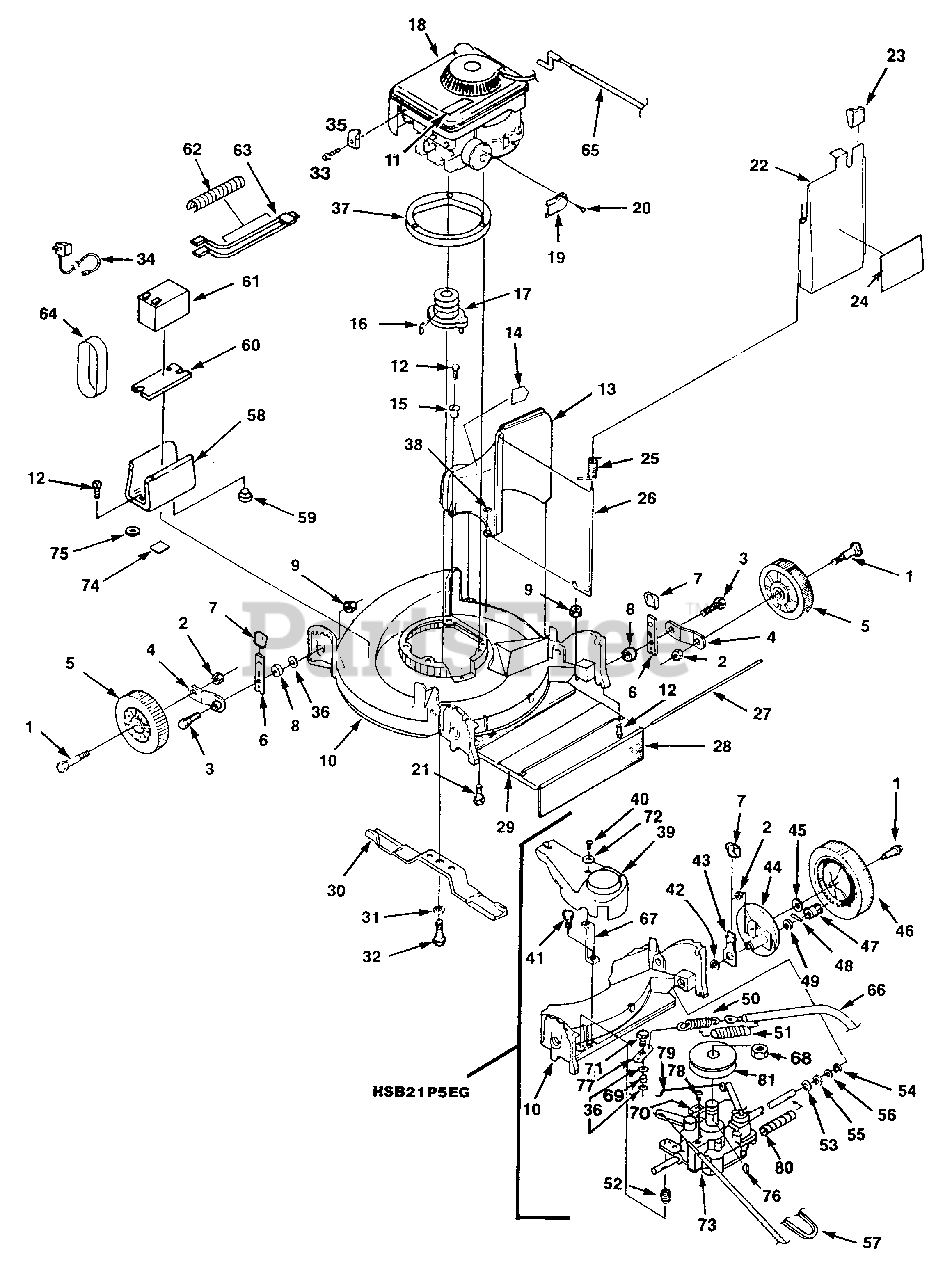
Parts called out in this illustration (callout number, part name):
1	AXLE ASSY.
2	NUT - Jam 3/8-16
3	BOLT-Hgt. adj.
4	ARM - Wheel hgt. adj.
5	WHEEL & TIRE
6	SPRING - Index (Front)
7	KNOB - Index sprg.
8	SPACER - Wheel hgt. adj.
9	NUT - Flange 5/16-18
10	DECK - 21"
11	DECAL - Blade Warning
12	SCREW 1/4-20 x 3/4"
13	CHUTE - Discharge
14	DECAL-CPSC
15	EYELET - Stimpson
16	KEY - Woodruff
17	ADAPTER - Blade
18	ENGINE
19	DEFLECTOR
20	SCREW - #8-32 x 3/8"
21	SCREW - 3/8-16 x 2 1/4"
22	DOOR - Chute
23	KNOB - Index sprg.
24	DECAL - Door (warning)
25	SPRING - Chute door
26	PIN - Hinge
27	ROD - Drag flap
28	FLAP - Drag
29	COVER - Drag
30	BAR - Cutter
31	WASHER - Lock 3/8"
32	SCREW - Hex hd. 3/8-24 x 1 1/4"
33	Screw - #10-16 x 5/8"
34	BATTERY CHARGER (120V)
35	CLAMP - Cable
36	WASHER - Flat (5/16")
37	RING - Engine
38	WASHER - Plain (1/4")
39	COVER - Drive
40	SCREW - 1/4-20 x 3/4"
41	SCREW - Hex #10-16
42	SPACER - Rear hgt. adj.
43	SPRING - Index
44	SUPPORT - Drive wheel
46	WHEEL & TIRE
47	PINION (L.H.)
48	PIN - Drive
50	SPRING - Ext.
51	COVER - Spring
52	SPRING - Compression
53	RING - Eaton
57	BELT - Traction
58	HOLDER - Battery
60	PAD - Battery
62	COVER - Harness
64	BAND - Rubber
65	ENGINE - Control
66	CABLE - Traction control
67	SUPPORT - cover
68	NUT - Metric (MIO)
69	SPACER - Bellcrank
70	CLAMP - Cable
71	SCREW - Hex hd. 5/16-18
72	WASHER - Plain
73	GEAR REDUCER (3 Speed)
74	SPACER - Battery holder
76	KEY - Woodruff
77	BELL CRANK
78	SCREW - 5/16-18 x 5/8"
79	LINKAGE - Shift
80	COVER - Drive shaft
81	PULLEY - Gear
